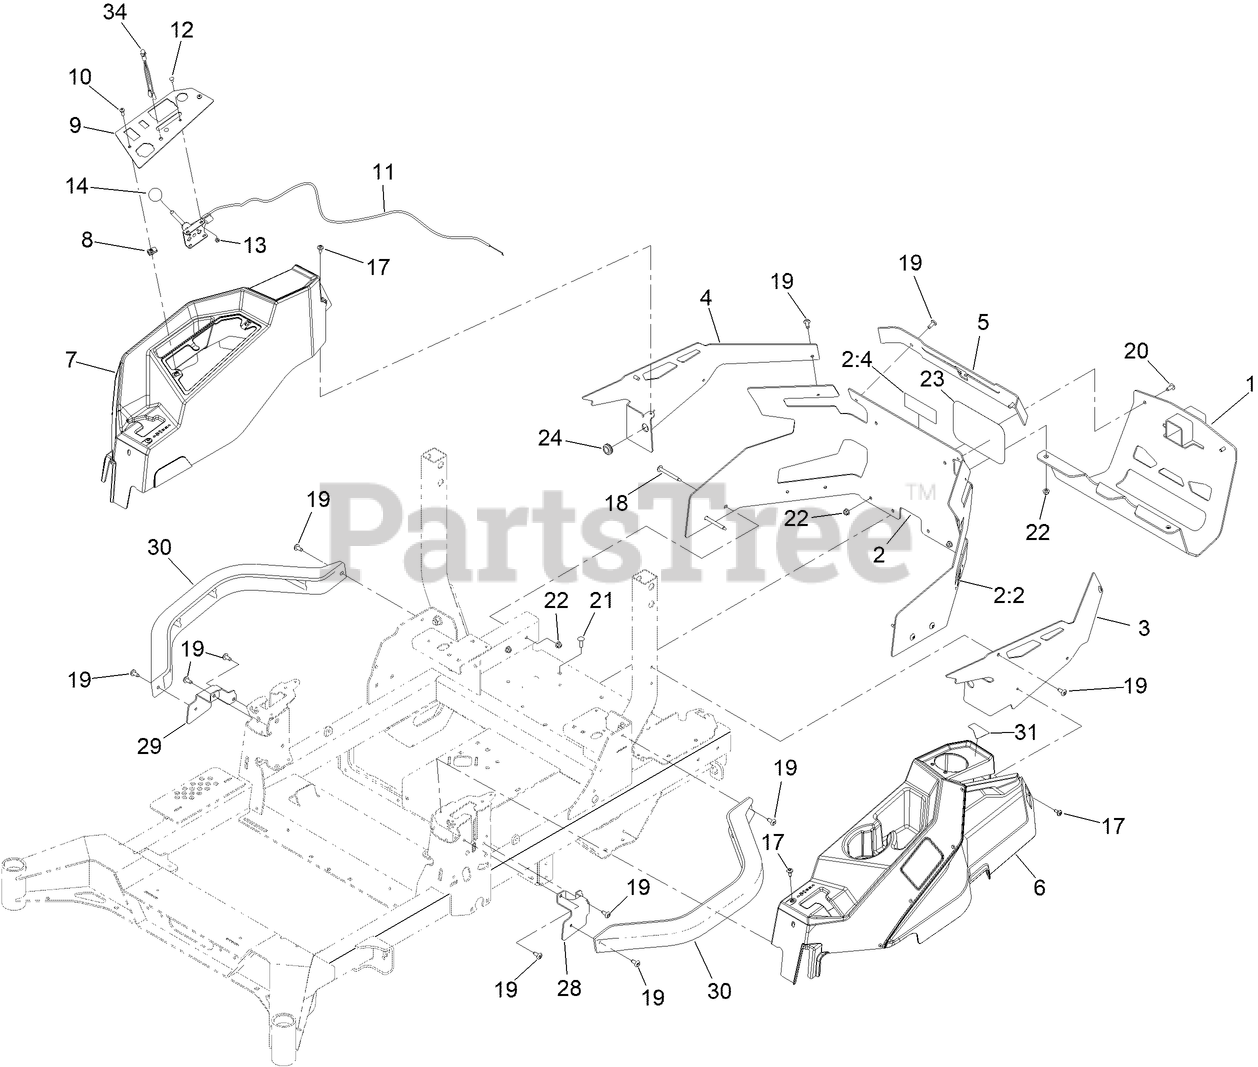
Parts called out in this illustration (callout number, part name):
1	MUFFLER GUARD ASM [BLACK]
2	REAR GUARD ASM
2:2	DECAL-WARNING
2:4	DECAL-HITCH
3	GUARD-REAR, LH
4	GUARD-REAR, RH
5	GUARD-REAR, TOP
6	LH POD ASM
7	RH POD ASM
9	PANEL-CONTROL
10	SCREW-PH
11	CABLE-CONTROL, THROTTLE
12	BOLT-CARR
13	NUT-LOCK, NI
14	KNOB-BALL
17	SCREW-SHOULDER
18	SCREW-TORX
20	SCREW-TORX
21	SCREW-CARR
22	NUT-HF, NI
23	DECAL
24	GROMMET
28	BRACKET-MOUNT, LH
29	BRACKET-MOUNT, RH
30	TUBE-POD
31	DECAL-FUEL FILL
34	INDICATOR-LED, RED
